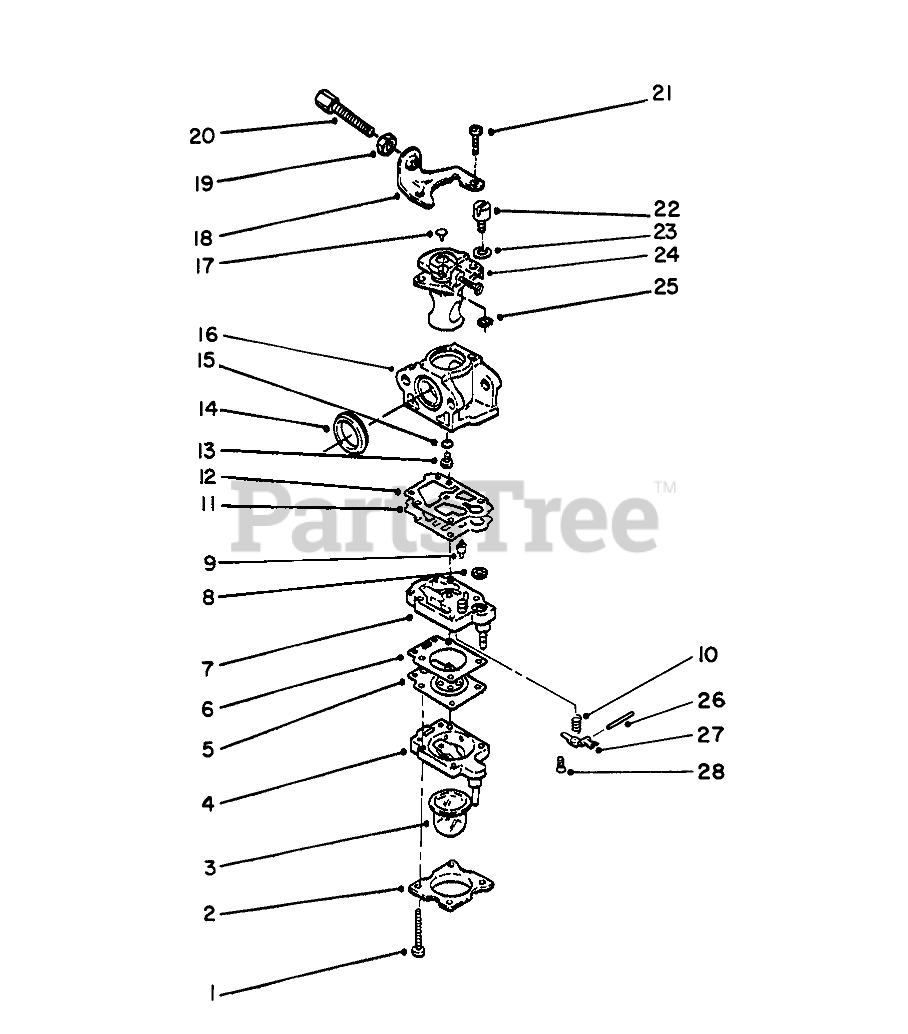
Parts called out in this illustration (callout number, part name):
1	Screw
2	Cover-Primer
3	PRIMER PUMP
4	Body-Primer
5	DIAPHRAGM
6	DIAPHRAGM GASKET
7	Body Assembly-Fuel Pump (Incl. Ref. #8)
8	SCREEN
9	NEEDLE VALVE
10	Spring
11	DIAPHRAGM
12	DIAPHRAM GASKET
13	MAIN JET
14	RUBBER CARB GASKET
15	MAIN JET O-RING
16	Body-Carburetor (Ref.)
18	BRACKET
19	LOCKNUT
20	ADJUSTING SCREW
21	SCREW
22	Holder-Wire
23	WASHER
24	THROTTLE VALVE
27	Lever
28	Screw
